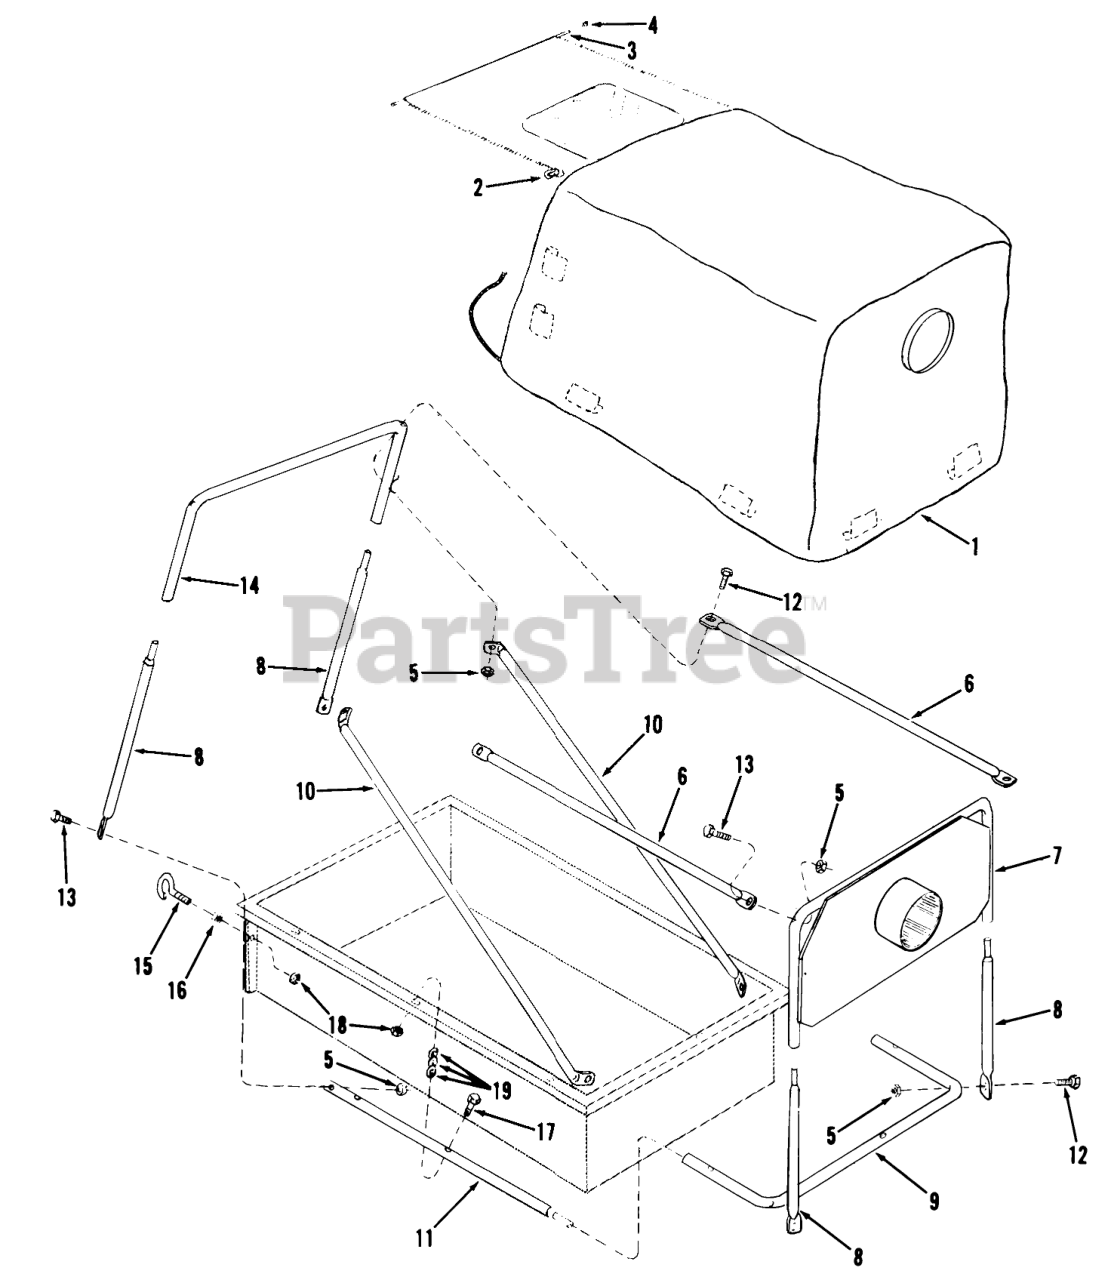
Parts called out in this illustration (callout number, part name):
1	Cart Cover
2	5/16 DIA HOOK
3	CANOPY ROD
4	RUBBER CAP
5	Nut
6	Top Tube
7	Front Hose Adapter
8	Upright Brace
9	U-Tube
10	Cross Tube
11	Side Tube
12	Bolt
13	Bolt
14	U-Tube
15	EYE BOLT
16	Nut
17	Bolt 1/4-20 X 1 1/2
18	Nut
